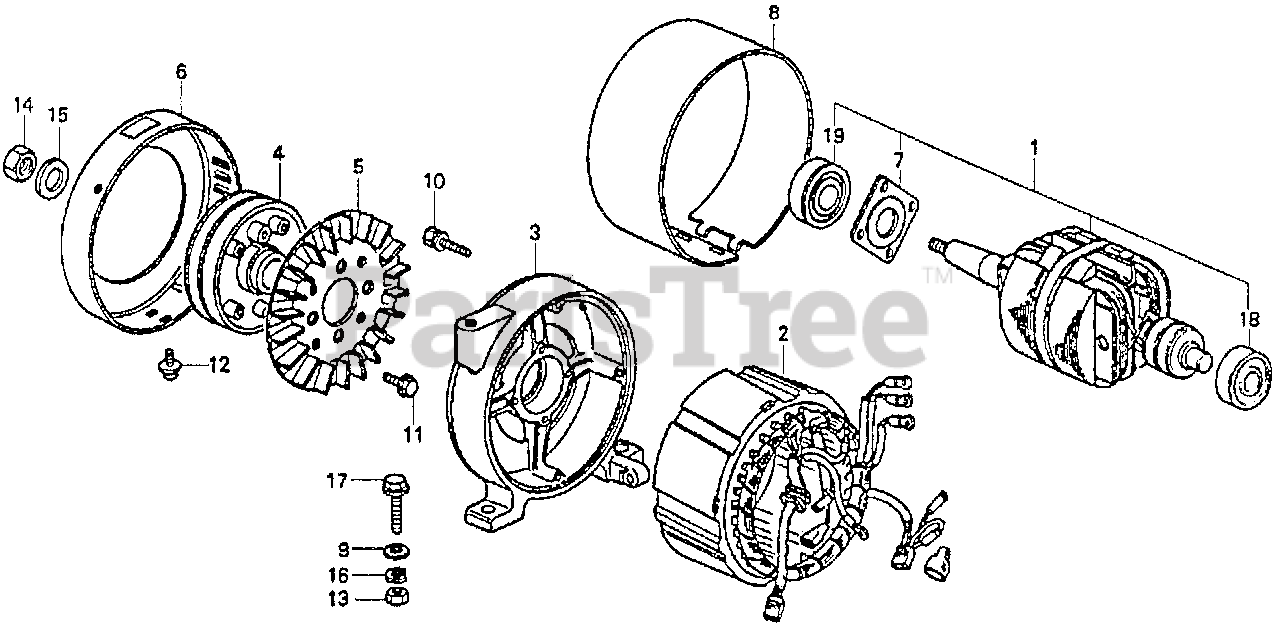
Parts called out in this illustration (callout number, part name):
3	HOUSING, FR. *NH31* (MCKINLEY WHITE)
4	PULLEY, ALTERNATOR (NOT AVAILABLE)
6	COVER, FAN *NH31* (MCKINLEY WHITE)
7	PLATE, BEARING SETTING
8	COVER, STATOR *NH31* (MCKINLEY WHITE)
9	WASHER, EX. MANIFOLD
10	BOLT-WASHER (5X20) (NOT AVAILABLE)
11	BOLT-WASHER (6X12)
12	SCREW-WASHER (5X10)
13	NUT, HEX. (10MM)
14	NUT, HEX. (18MM) (NOT AVAILABLE)
15	WASHER, FLAT (18MM) (NOT AVAILABLE)
16	WASHER, SPRING (10MM)
17	BOLT, FLANGE (10X32)
18	BEARING, RADIAL BALL (6304UU)
19	BEARING, RADIAL BALL (6306UU) (NOT AVAILABLE)
